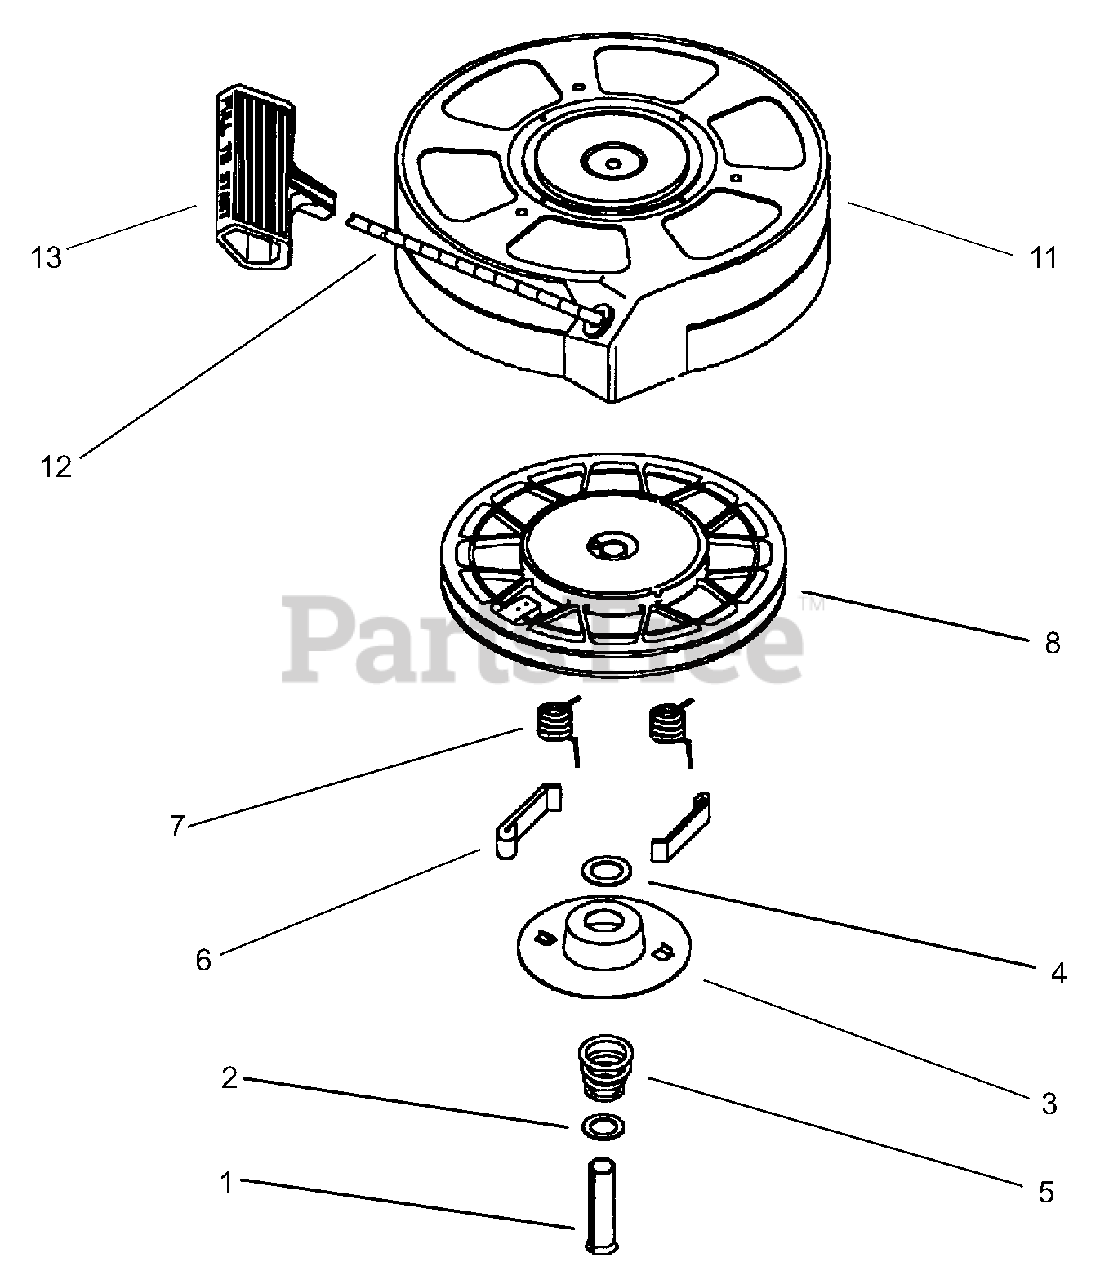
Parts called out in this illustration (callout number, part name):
1	Spring Pin (Incl. 4)
2	Washer
3	Retainer
4	Washer
5	Brake Spring
6	Starter Dog
7	Dog Spring
8	Pulley & Rewind Spring Ass'y.
11	Starter Housing Ass'y. (40 degree grommet)
12	Starter Rope (98" X 9/64" dia.)
13	Starter Handle
